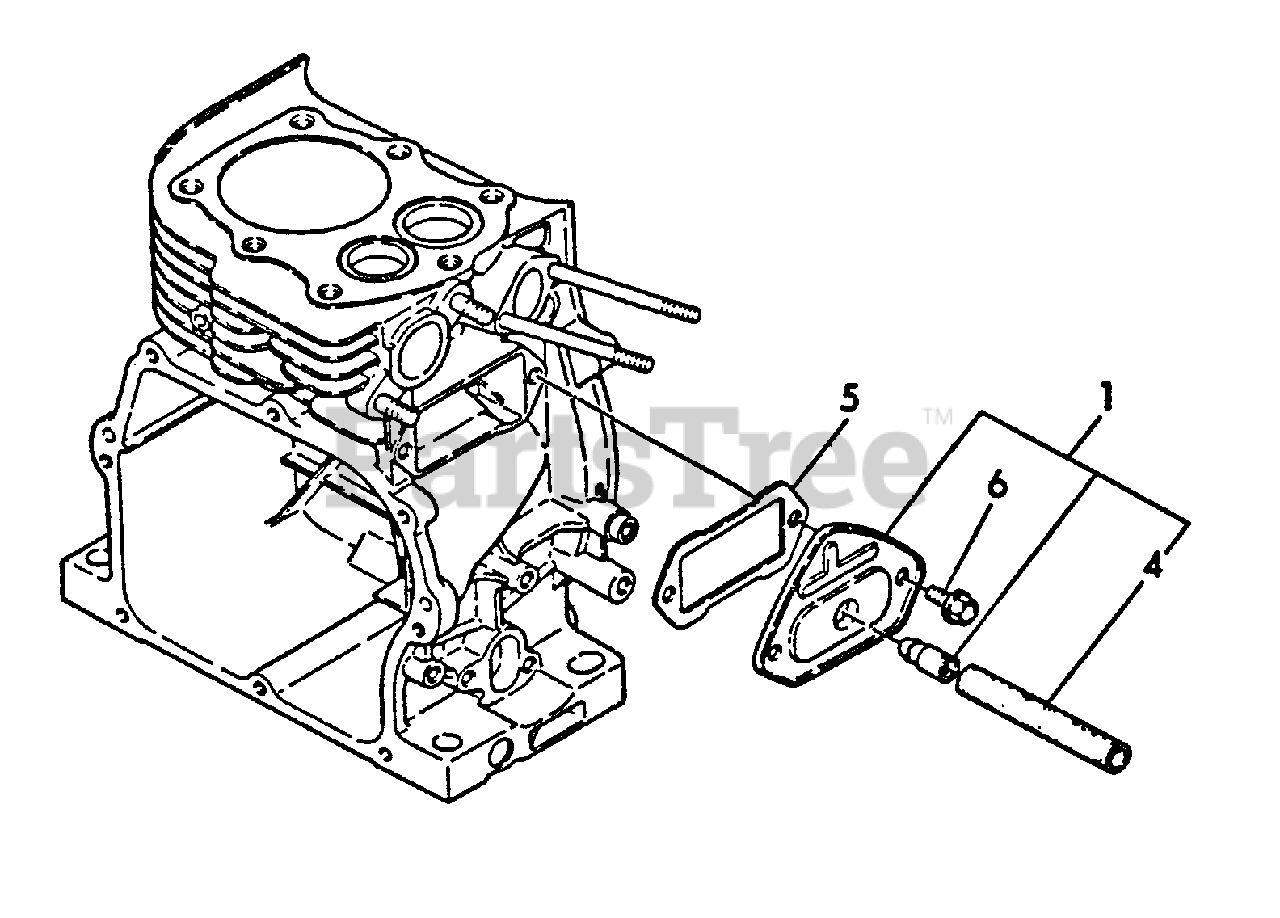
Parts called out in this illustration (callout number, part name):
1	BREATHER ASSY
4	PIPE, BREATHER
5	GASKET
6	BOLT - 6×8 -- PLATED
